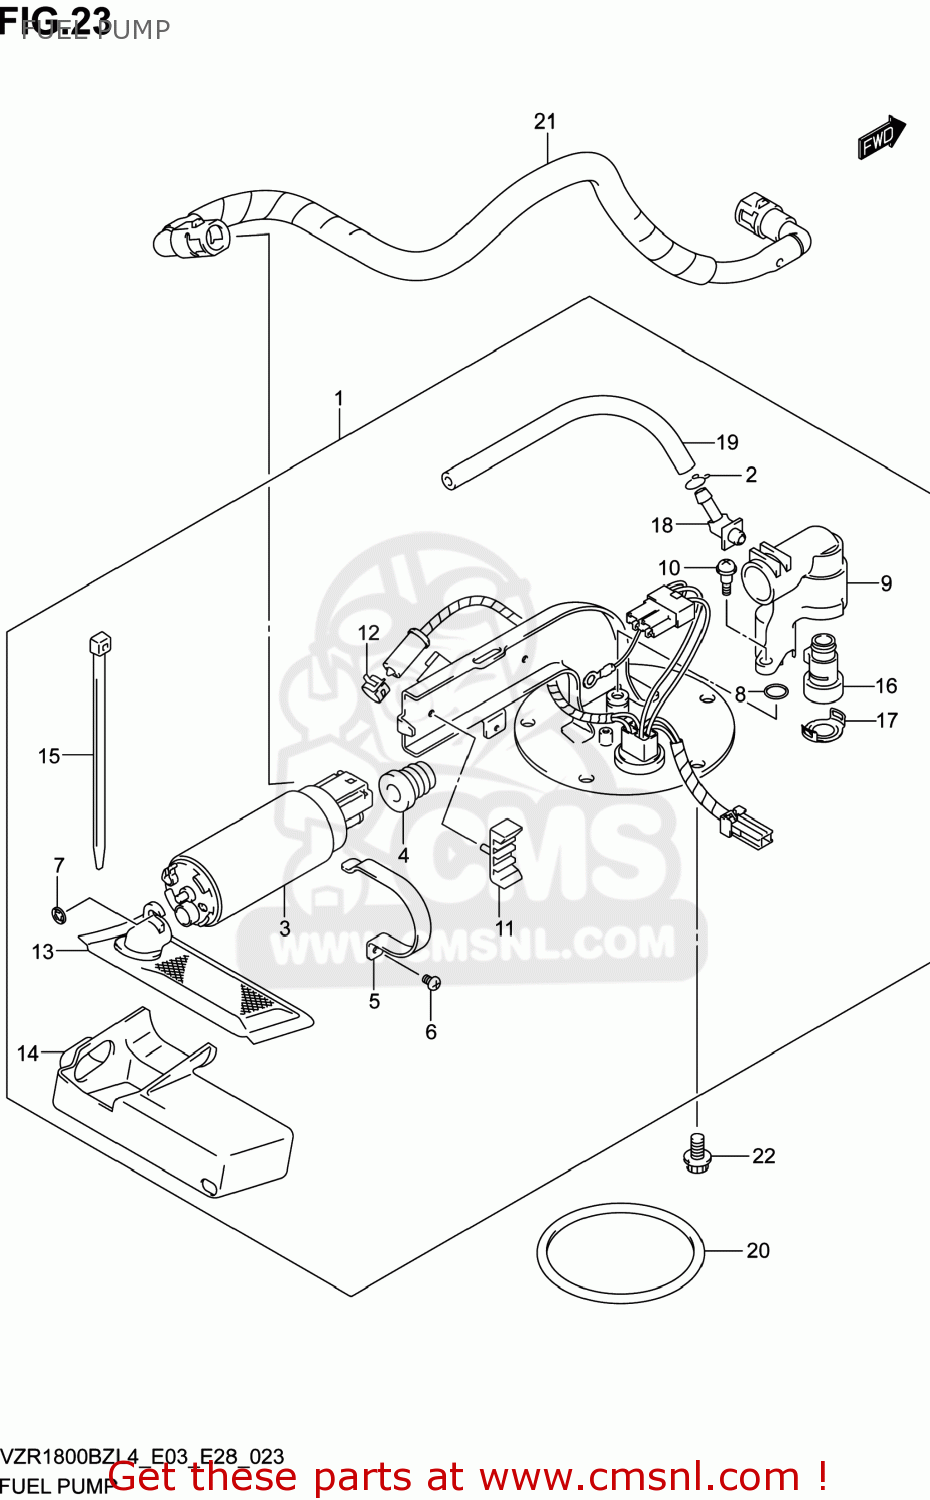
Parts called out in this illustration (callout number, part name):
1	PUMP ASSY,FUEL
2	CLIP
3	PUMP,FUEL
4	INSULATOR
5	HOLDER
6	SCREW
7	PLATE
8	O RING
9	ADAPTER
10	SCREW
11	INSULATOR
12	CLAMP
13	STRAINER,FUEL
14	COVER,FILTER
15	BAND
16	REGULATOR,PRESSURE
17	CLIP
18	JOINT
19	TUBE
20	O RING,FUEL PUMP
21	HOSE,FUEL
22	BOLT
